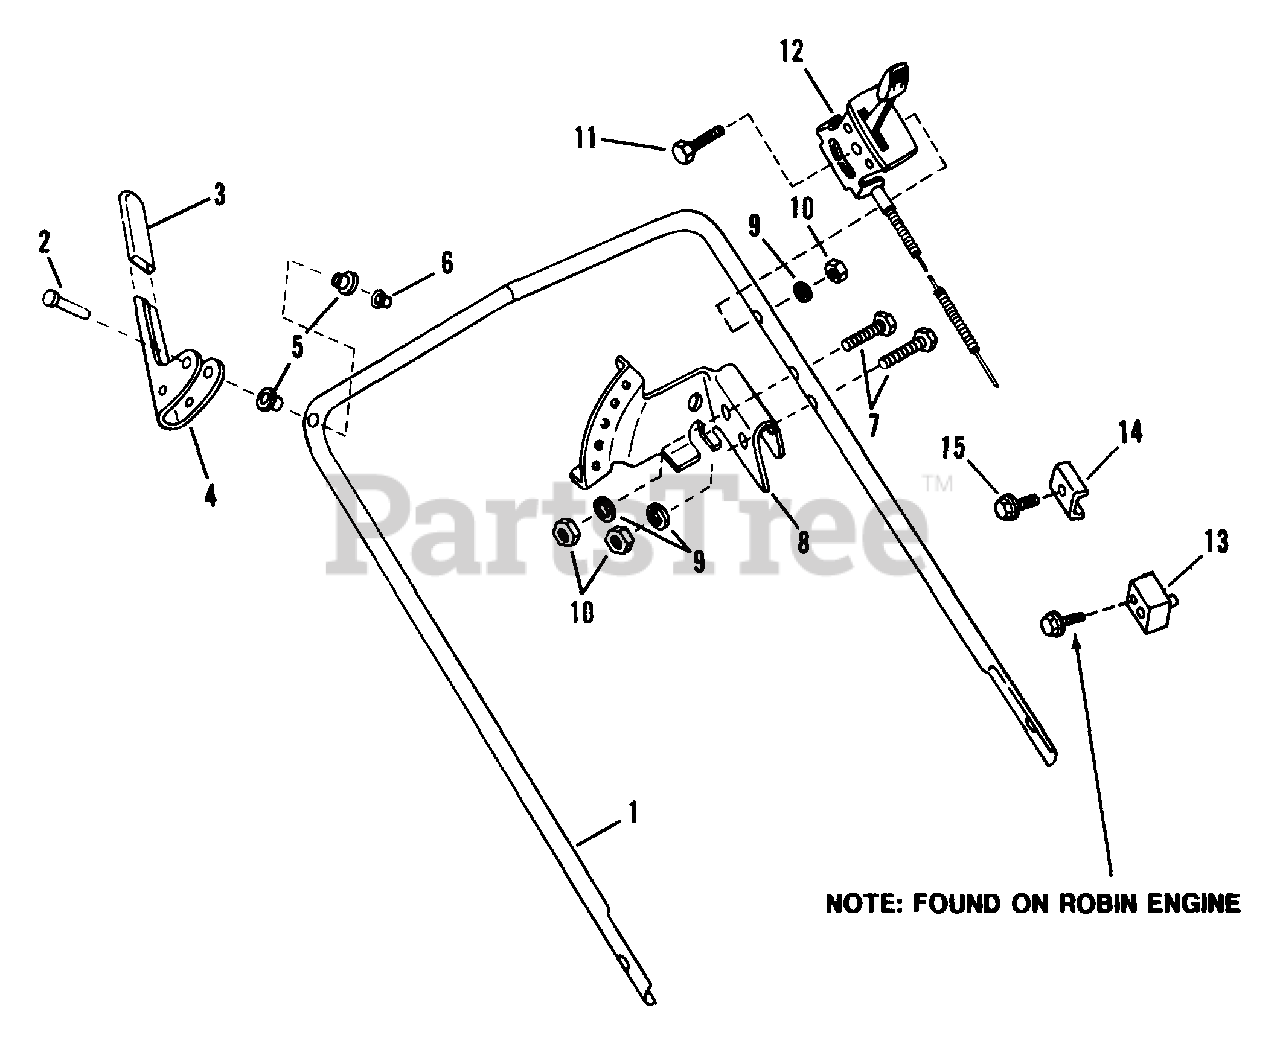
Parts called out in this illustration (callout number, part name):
1	HANDLE, Upper
2	PIN, Clutch Handle
3	GRIP
4	HANDlE, Wheel Drive
5	BUSHING
6	NUT, Push
7	SCREW, 1/4-28 x 1 3/8" Hex Head Cap
8	SECTOR, Speed
9	WASHER, 1/4 Internal Tooth Lock
10	NUT, 1/4-28 Hex
11	SCREW, 1/4-28 x 1 3/4 Hex Head Cap
12	THROTTLE, Control
13	SPACER
14	CLAMP, Casing (Briggs)
15	SCREW, #10-18 x 5/8" Self-Tapping
